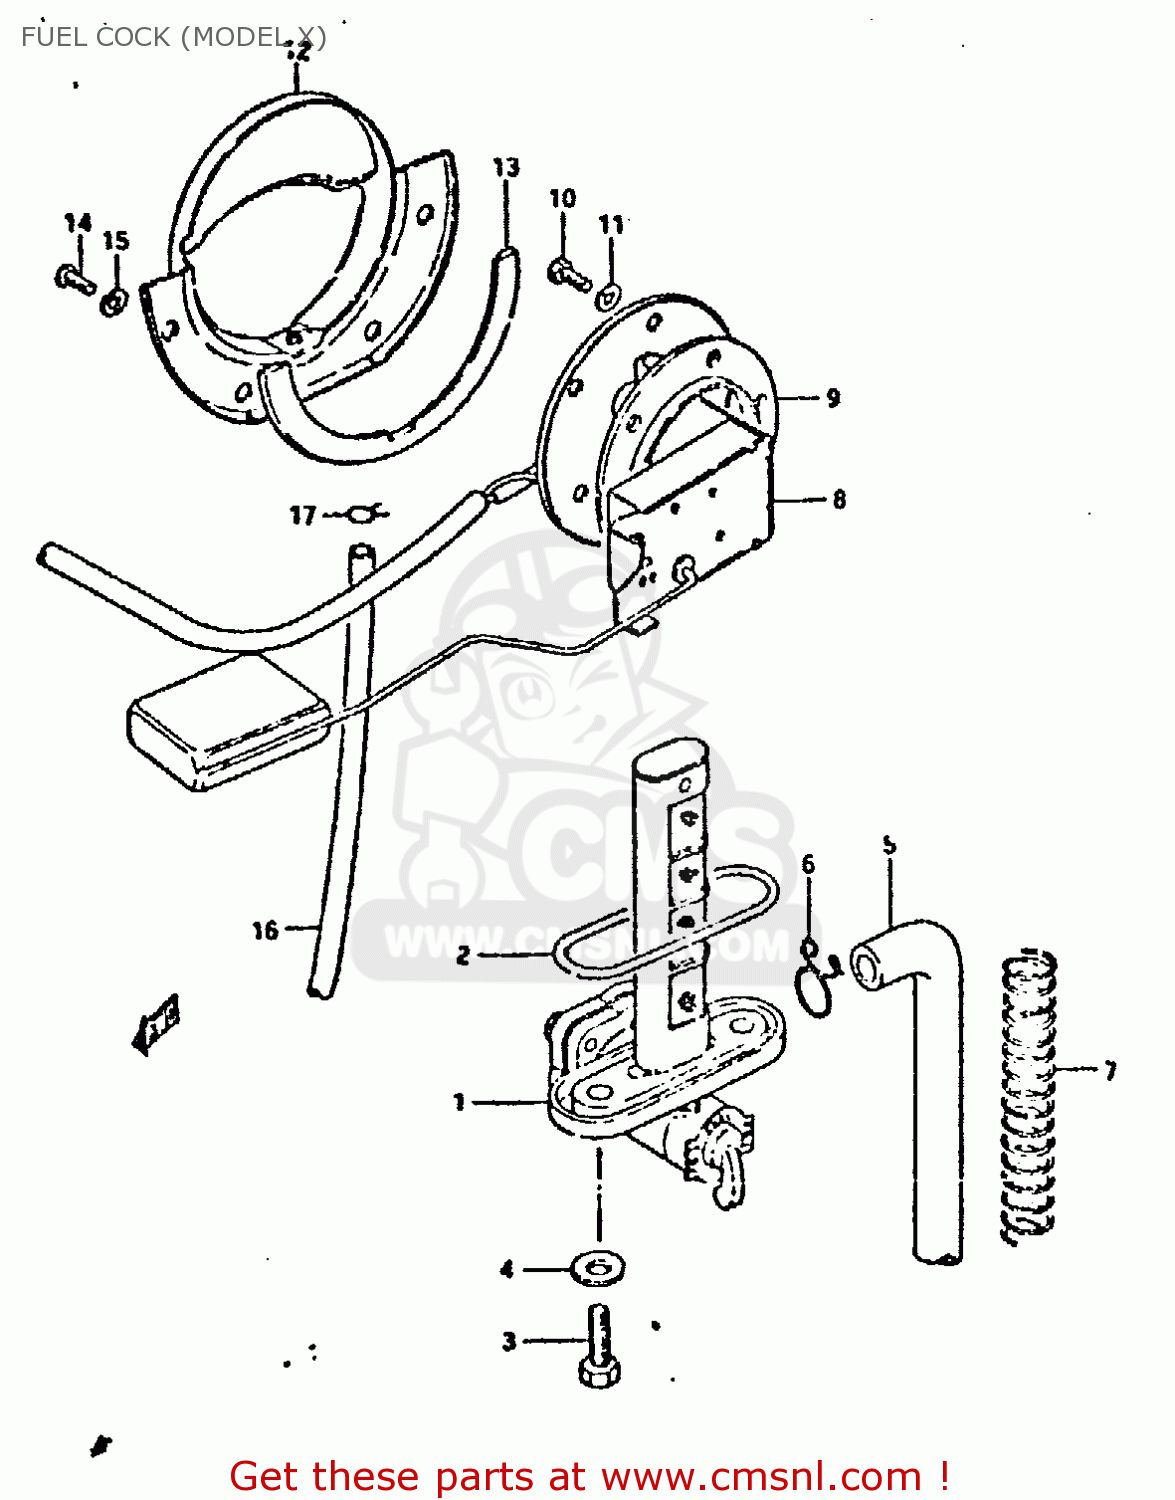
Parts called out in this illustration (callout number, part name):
1	COCK ASSEMBLY,FUEL
2	O RING
3	SCREW (6X25)
4	GASKET
5	HOSE
6	CLIP
7	SPRING
8	GAUGE, FUEL LEVEL (24L)
9	GASKET,FUEL LEVEL GAUGE (NAS)
10	BOLT
11	LOCK WASHER
12	PLATE,FUEL DRAIN
13	GASKET,FUEL DRAIN PLATE (NAS)
14	SCREW
15	LOCK WASHER
16	HOSE,FUEL
17	CLIP
